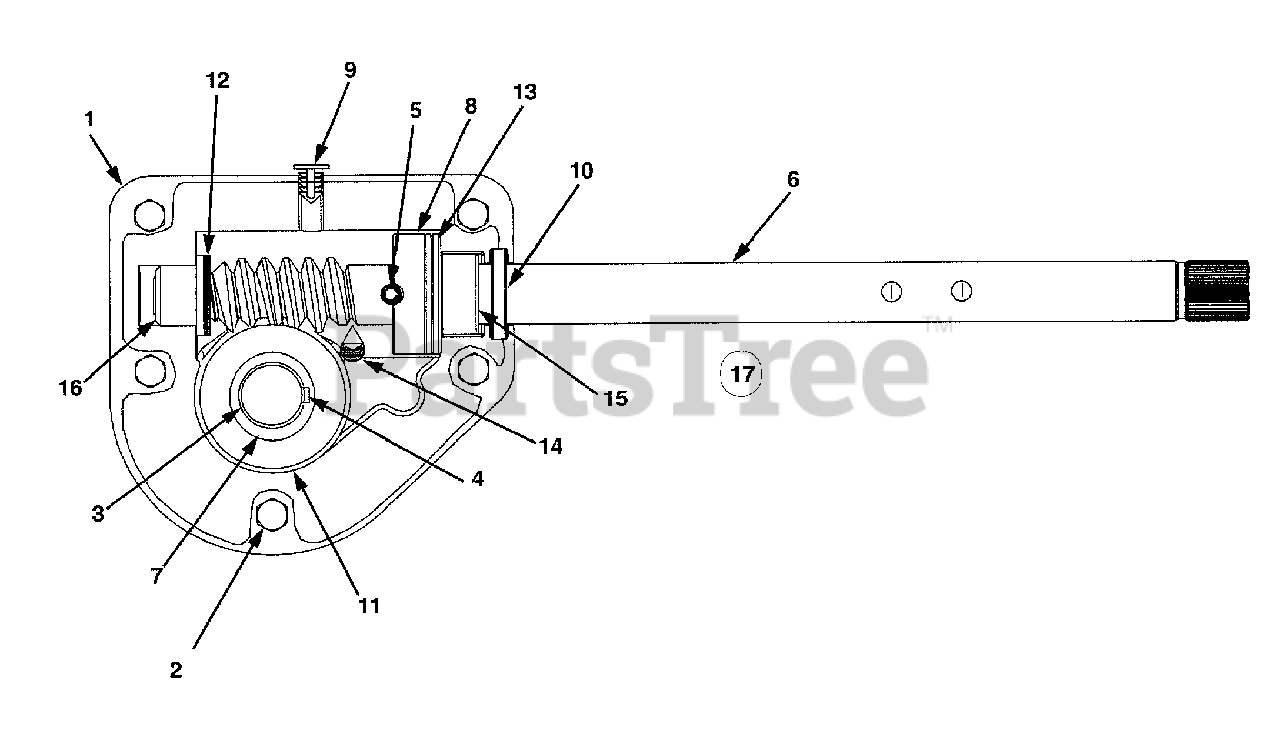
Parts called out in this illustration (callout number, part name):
1	Housing-R.H.
2	Hex Screw 1/4-20 x .75
3	Spiral Axle 22"
4	Key
5	Pin-Spiral
6	Shaft-Worm
7	Gear-Worm
8	Collar-Thrust
10	Seal-Oil
11	Washer-Flat
12	Washer-Flat
13	Washer-Flat
14	Grease
15	Bearing-Flange
16	Bearing-Flange
17	Assembly, Complete 22"
